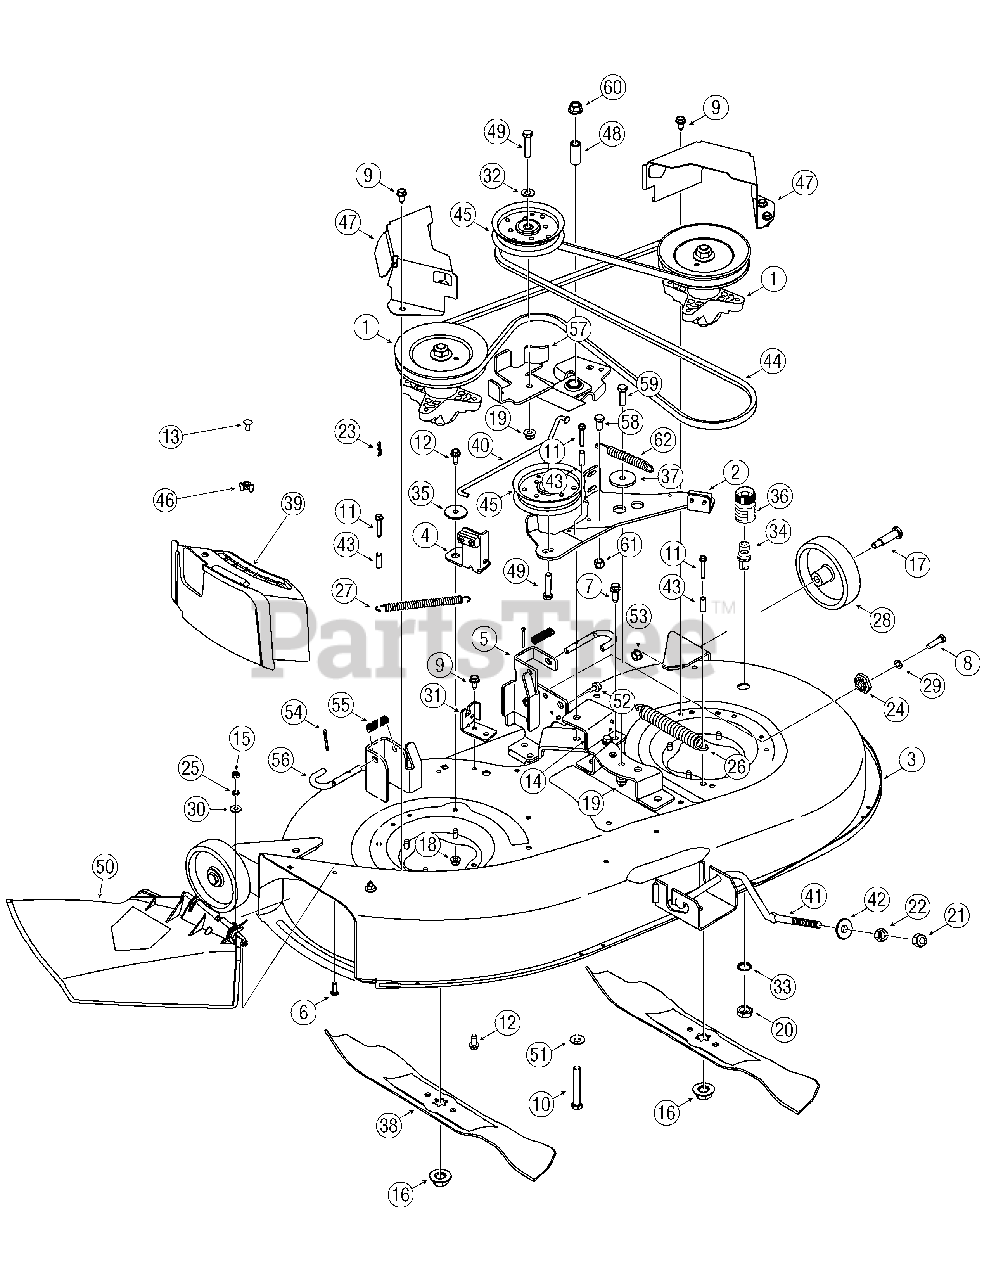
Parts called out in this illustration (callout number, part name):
1	Spindle Assembly, Pul, 6.23" Dia
6	Screw, 1/4-20, .75, Gr5
7	Screw, 3/8-16, 1.00
8	Screw, 5/16-18, 1.250
9	Screw, 5/16-12, 0.750
10	Screw, 7/16-20, 3.00, Gr5
11	Screw, 1/4-20, 1.500
12	Screw, 5/16-18, .75
13	Carriage Screw, , 1/4-20 x .62
15	Nut, Hex, 1/4-20, Gr5
16	Nut, Flange, 5/8-18
17	Screw, Shldr, .498 x 1.53, 3/8-16
18	Nut, Flange Lock, 5/16-18,
19	Nut, Flange Lock, 3/8-16, GrF
20	Nut, Hex, M16-1.5
21	Nut, Hex Lock, 1/2-13, Gr8
22	Nut, Hex, 1/2-13, Gr5
23	Pin, Cot, .072 Dia. x 1.13 Lg
24	Gear, Deck Adjustment
25	Nut, Push, .25 ID x .50
26	Spring, Exten. , .94 Dia. x 6.74
27	Spring, Exten. , .50 Dia. X 6.375
28	Wheel, Deck 5.0 x 1.38
29	Washer, Lock, 5/16
30	Washer, Bell, .265 x.75 x .062
32	Washer, Flat, .406 x .875 x .059
33	Washer, Lock
34	Deck Water Nozzle
35	Spacer, Shoulder, .5000 x .1475
36	Water Nozzle Adapter
37	Spacer, Shoulder, .8840 x .190
38	Blade, 21.23", Star 3-in-1
39	Mulch Plug
40	Control Rod, Brake
41	Deck Rod, Front Adjustable
42	Pivot Cup, Deck Lift
43	Spacer, .260 x .372 x 1.030
44	Belt, V-Type
45	Idler Pulley, 4.25" Dia.
46	Wing Nut, 1/4-20
48	Spacr, .455 ID x .680 OD
49	Screw, 3/8-16 x 1.75
50	Chute Assembly, Discharge
51	Bell Washer, .45 x 1.00 x .062
52	Bumper
53	Flange Lock Nut, 3/8-16
55	Comp. Spring, .531OD x 1.75 Lg.
56	Deck Release Rod
58	Screw, 3/8-16 x .75
59	Screw, 3/8-16 x 1.25
60	Flange Lock Nut, 7/16-20
61	Hex Lock Nut, 3/8-24
62	Extension Spring, .53 OD x 4.75
